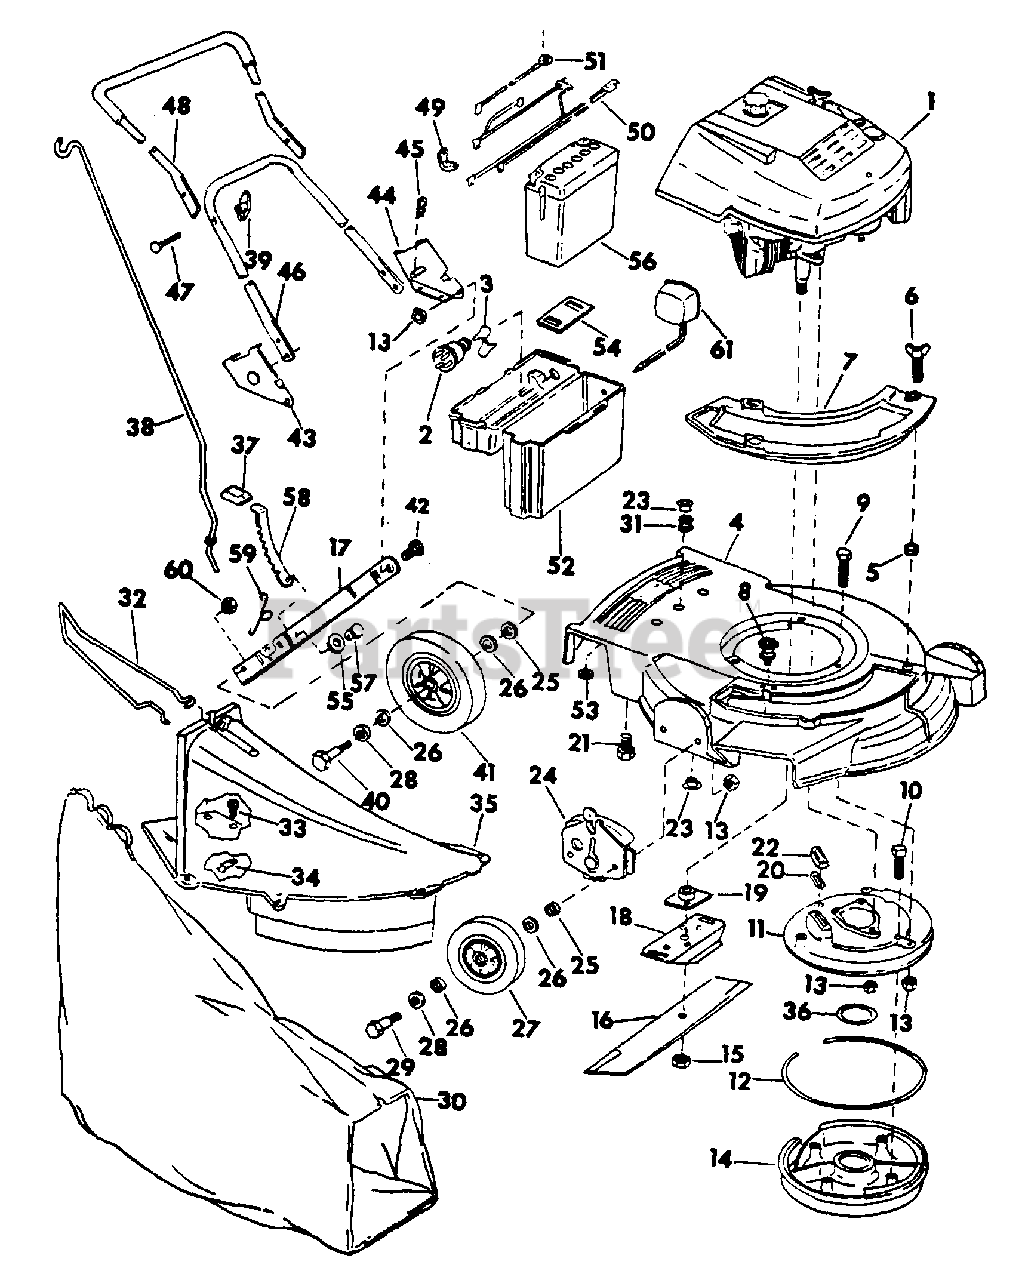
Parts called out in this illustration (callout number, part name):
1	ENGINE, IH
4	HOUSING ASSY, 21 IN.
5	NUT, GROMMET
6	SCREW, WING
7	COVER, CHUTE OPENING
8	SCREW, SHOULDER
9	SCREW, MUFFLER PLT TO HSG
10	SCREW, MUFFLER TO PLATE
11	PLATE, MUFFLER
12	GASKET, MUFFLER OUTSIDE
14	COVER, MUFFLER
16	BLADE, 21 IN.
18	STIFFENER, BLADE
19	COLLAR & PLATE
20	GASKET, EXHAUST
21	SCREW, HANDLE BRACKET
22	SLEEVE, EXHAUST GASKET
23	SPACER, FLANGED
24	ADJUSTMENT, HEIGHT
26	WASHER, FELT
27	WHEEL AND TIRE
28	WASHER, WHEEL BOLT HD
29	BOLT, WHEEL FRT SHOULDER
32	GUARD, WHEEL
35	CHUTE ASSY
36	GASKET, MUFFLER INSIDE
38	ROD, GRASS BAG
40	BOLT, REAR WHEEL
41	WHEEL & TIRE - 8 IN. REAR
43	BRACKET & PIN, RH
44	BRACKET & PIN, LH
46	HANDLE, BOTTOM
48	HANDLE & GRIP, TOP
49	POD, INSULATION
52	BOX, BATTERY
53	WASHER, BATTERY MTG BRACKET
54	STRAP, BATTERY BOX MTG
55	WASHER, SPRING
56	BATTERY, DRY CHARGED
57	PIN, HEIGHT ADJ LEVER
58	LEVER, REAR HGT ADJ
61	CHARGER, TRICKLE
